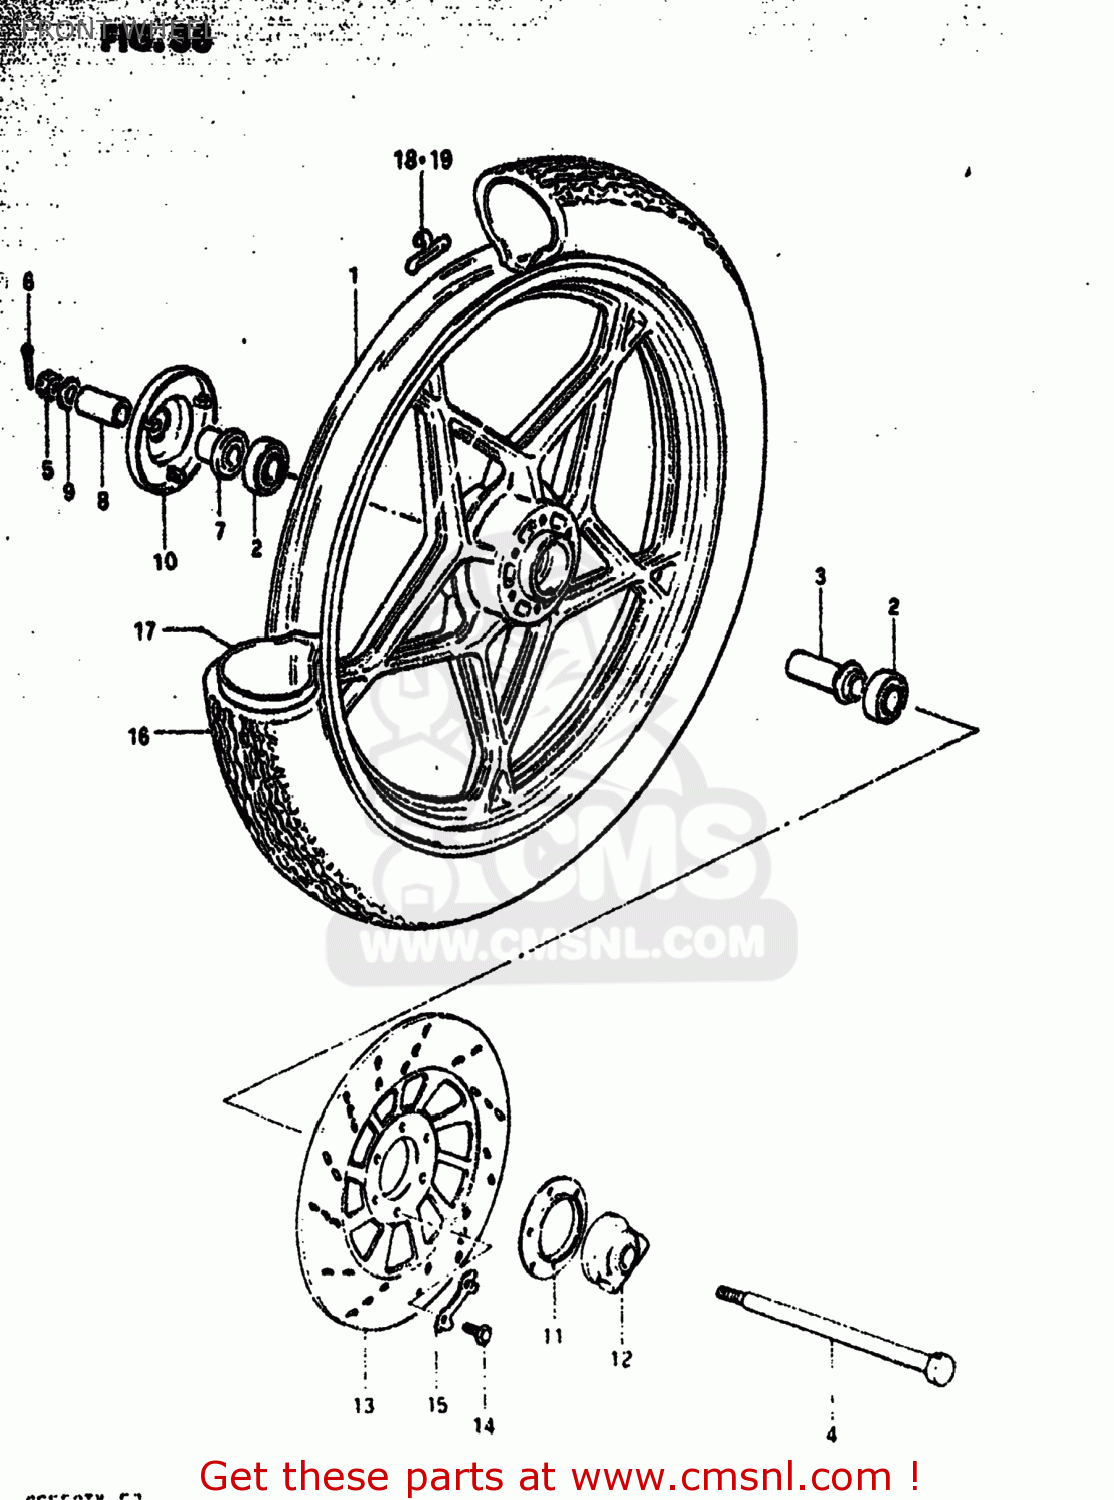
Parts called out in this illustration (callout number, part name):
1	WHEEL, FRONT
2	BEARING
3	SPACER,FR HUB BEARING
4	AXLE,FRONT
5	NUT 12MM
6	COTTER PIN
7	SPACER,FR HUB BEARING,R
8	SPACER(15X22X30)
9	WASHER
10	COVER,FR HUB,R
11	DUST SEAL,SPEEDOMETER GEAR BOX
12	BOX ASSEMBLY,SPEEDOMETER GEAR
13	DISC,BRAKE
14	BOLT(8X25)
15	WASHER
16	TIRE,FRONT
17	TUBE,INNER
18	BALANCER,WHEEL
19	BALANCER,WHEEL
